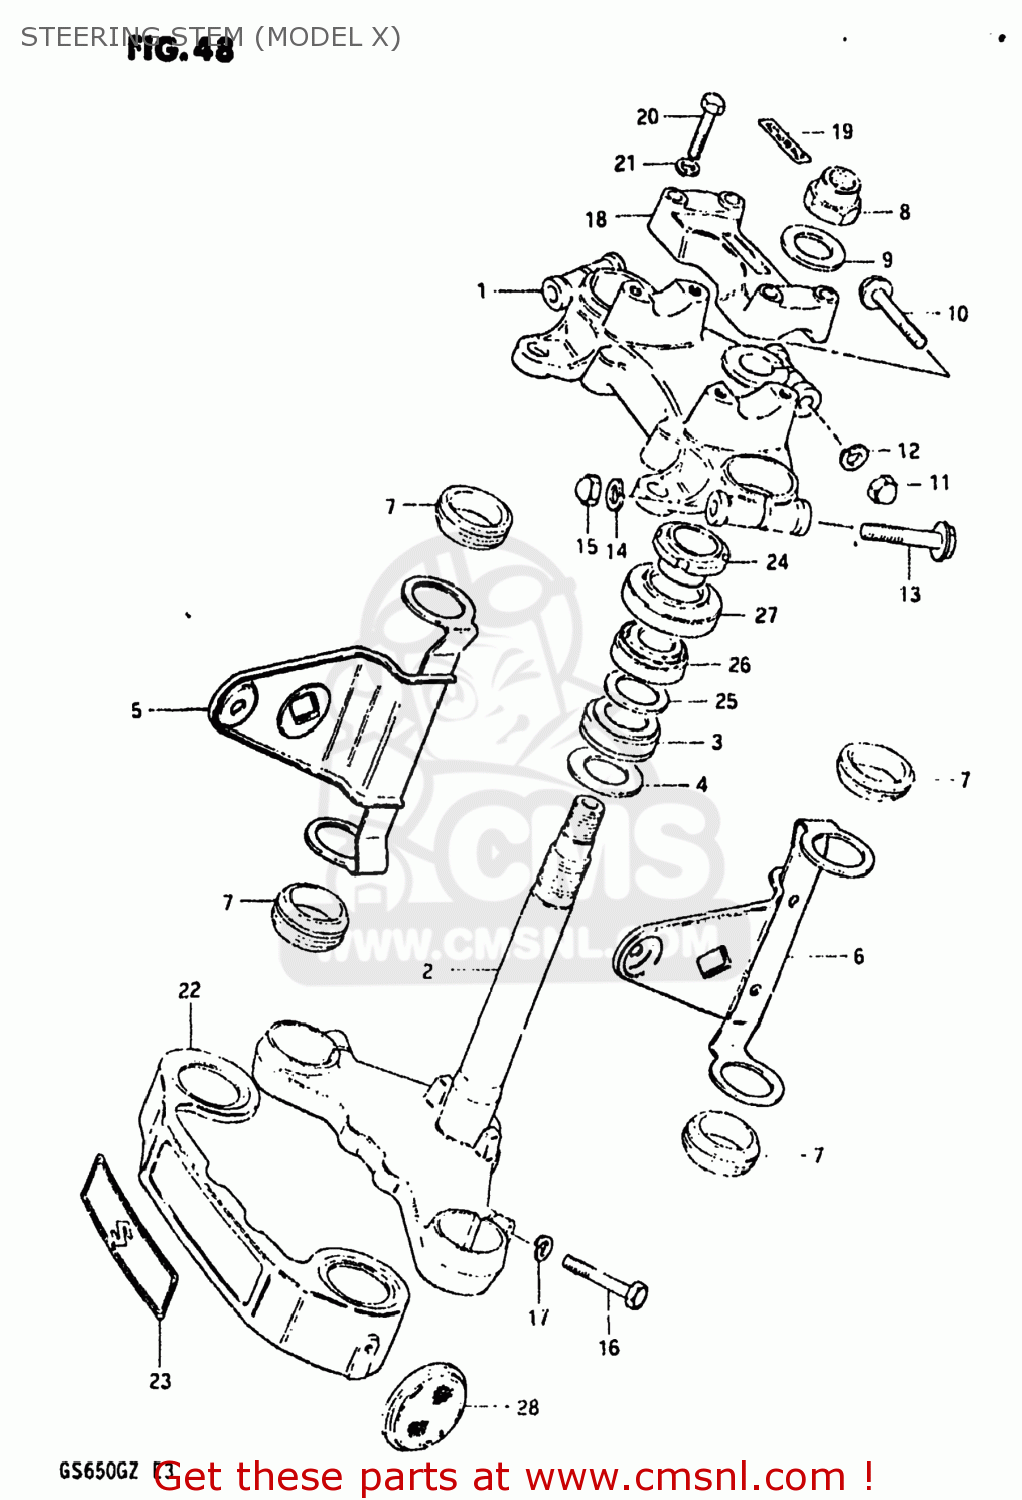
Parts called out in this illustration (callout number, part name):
1	HEAD,STEERING STEM
2	STEM,STEERING
3	BEARING
4	WASHER,THRUST
5	BRACKET,HEADLAMP,RIGHT
6	BRACKET,HEADLAMP,LEFT
7	CUSHION,HEADLAMP BRACKET
8	NUT,FR FORK UPR BRACKET
9	WASHER
10	BOLT
11	NUT,M8X1.25X12
12	LOCK WASHER
13	BOLT 10X55
14	LOCK WASHER
15	NUT
16	BOLT 10X40
17	LOCK WASHER
18	HOLDER,HANDLEBAR
19	EMBLEM,HANDLE CLAMP
20	BOLT
21	LOCK WASHER
22	COVER,FRONT FORK
23	EMBLEM
24	NUT,STEERING STEM
25	WASHER(18.5X24X1)
26	TAPER,ROLLER BEARING
27	DUST SEAL,STEERING,UPPER
28	REFLEX REFLECTOR,RR
